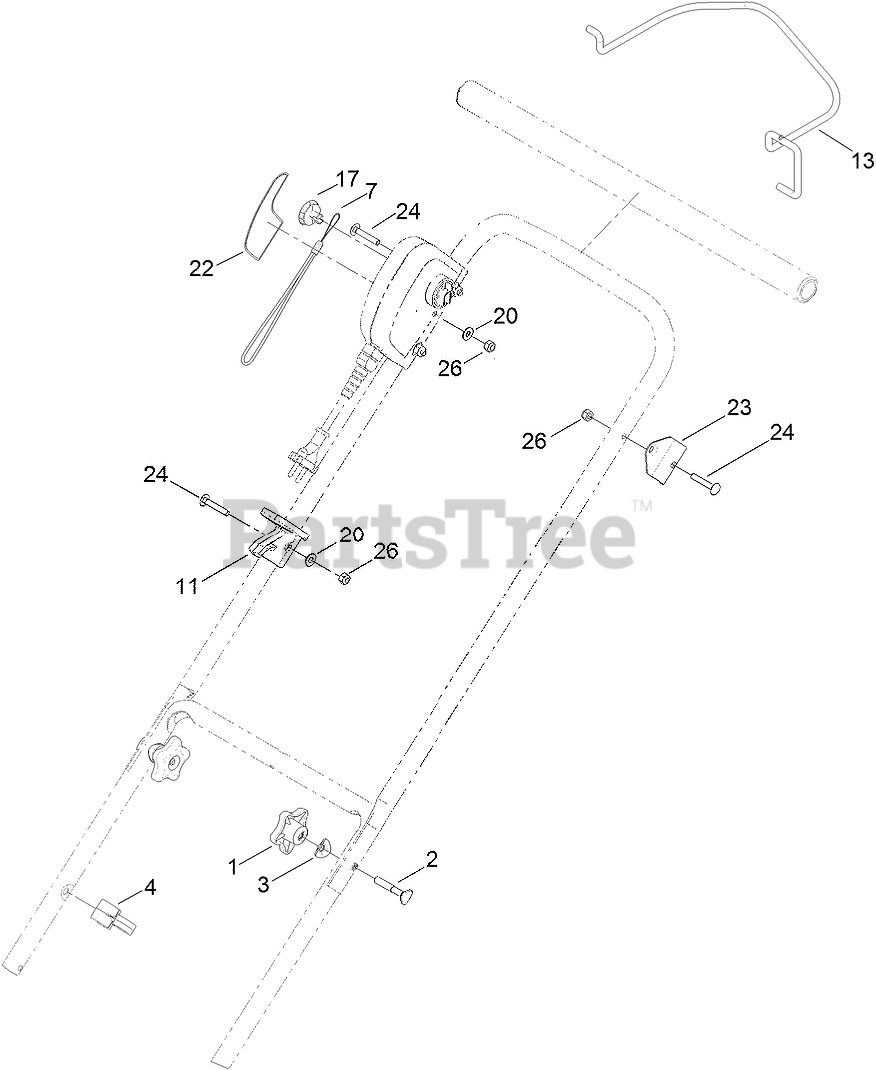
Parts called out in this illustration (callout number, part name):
1	KNOB-HANDLE
3	WASHER
4	GUIDE-CABLE
7	CORD-KEY
11	LOCK-CORD
17	KEY-BAIL
20	WASHER-FLAT
22	DECAL-OPERATION
23	BRACKET-BAIL
24	SCREW-CARR
26	NUT-LOCK, NI
